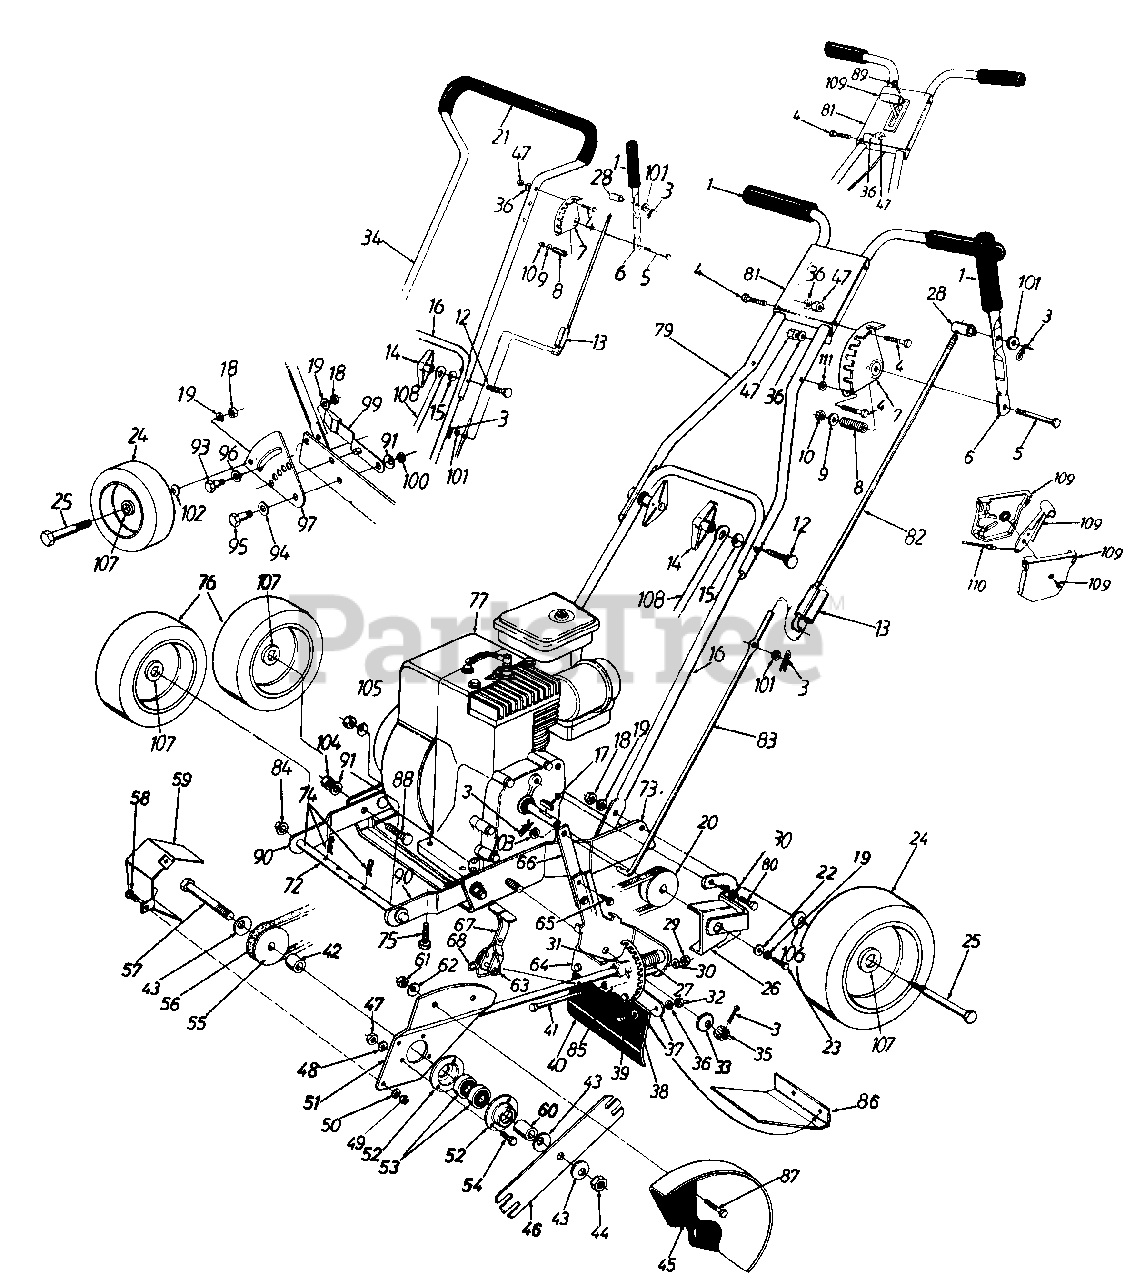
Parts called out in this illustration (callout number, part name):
1	Foam Grip
3	Cotter Pin 5/16" Dia.
4	Hex Bolt 1/4-20 x 1.25" Lg.
5	Hex Bolt 5/16-18 x 2" Lg.
8	Compression Spring 1.38" Lg.
9	Fl-Wash.344" I.D.
10	Hex L-Nut 5/16-18 Thd.
12	Curv. Hd. Bolt 5/16-18 x 2" Lg.
13	Clutch Rod Lock
14	Wing Nut Ass'y.
15	Saddle Wash.32" I.D. x .937"
18	Hex Nut 3/8-16 Thd.
19	L-Wash. 3/8" I.D.
20	Engine Pulley
21	Foam Grip
22	Fl-Wash.385" I.D.
23	Hex Bolt 3/8-24 x 1" Lg.
24	Rear Wheel Ass'y.- Bar Tread
25	Shoulder Bolt .498" Dia.
28	Ferrule
29	Hex Nut 5/16-18 Thd.
30	L-Wash. 5/16" I.D.
31	Spring Pin Spir. 1/4" Dia.
32	Hex Nut 1/4-20 Thd.
33	Bell-Wash.535" I.D.
34	Upper Loop Handle
35	Hex Slotted Nut 1/2-20 Thd.
36	L-Wash. 1/4" I.D.
39	Hex Bolt 1/4-20 x .62" Lg.
41	Hex Bolt 5/16-18 x 4.5" Lg.
42	Spacer 1.030" Lg.
43	Bell-Washer.63" I.D.
44	Hex Jam L-Nut 5/8-18 Thd.
47	Hex Nut 1/4-20 Thd.
48	L-Wash. 1/4" I.D.
49	Hex Nut 1/4-20 Thd.
50	L-Wash. 1/4" I.D.
53	Ball Bearing .62" I.D.
54	Hex Bolt 1/4-20 x .62" Lg.
55	3/8" "V"-Pulley
56	"V"-Belt
57	Hex Bolt 5/8-18 x 4.5" Lg.
58	Hex Bolt 1/4-20 x .625" Lg.
60	Sleeve .90" Lg.
61	Hex Nut 5/16-18 Thd.
62	Bell-Wash .345" I.D.
63	Spring Pin Spir. 1/4" Dia.
68	Torsion Spring
72	Axle 8.20" Lg. (Front)
75	Hex TT-Tap Scr. 3/8-16 x 1" Lg.
76	Front Wheel Ass'y.- Bar Tread
77	Engine
83	Lower Clutch Rod
84	Push Cap 1/2" Dia.
85	Spacer 3.765" Lg.
88	Ribbed Neck Bolt 3/8-24 x .8" Lg.
89	Self-Tap Scr. #10 x .5" Lg.
93	Shld. Bolt .5" Dia.
94	Bell-Wash.515" I.D.
95	Shld. Bolt .50" Dia.
96	Fl-Wash.51" I.D. x .94"
100	Hex Jam Nut 3/8-16 Thd.
101	Fl-Wash.344" I.D. x .62" O.D.
102	Wave Wash.51" I.D.
103	Fl-Wash.406" I.D. x .81" O.D.
104	Hex Nut 3/8-24 Thd.
105	Bell-Wash.396" I.D. x 1.14" O.D.
106	Bell-Wash.38" I.D. x .88" O.D.
107	Plastic Bearing
110	Throttle Wire 39" Lg.
